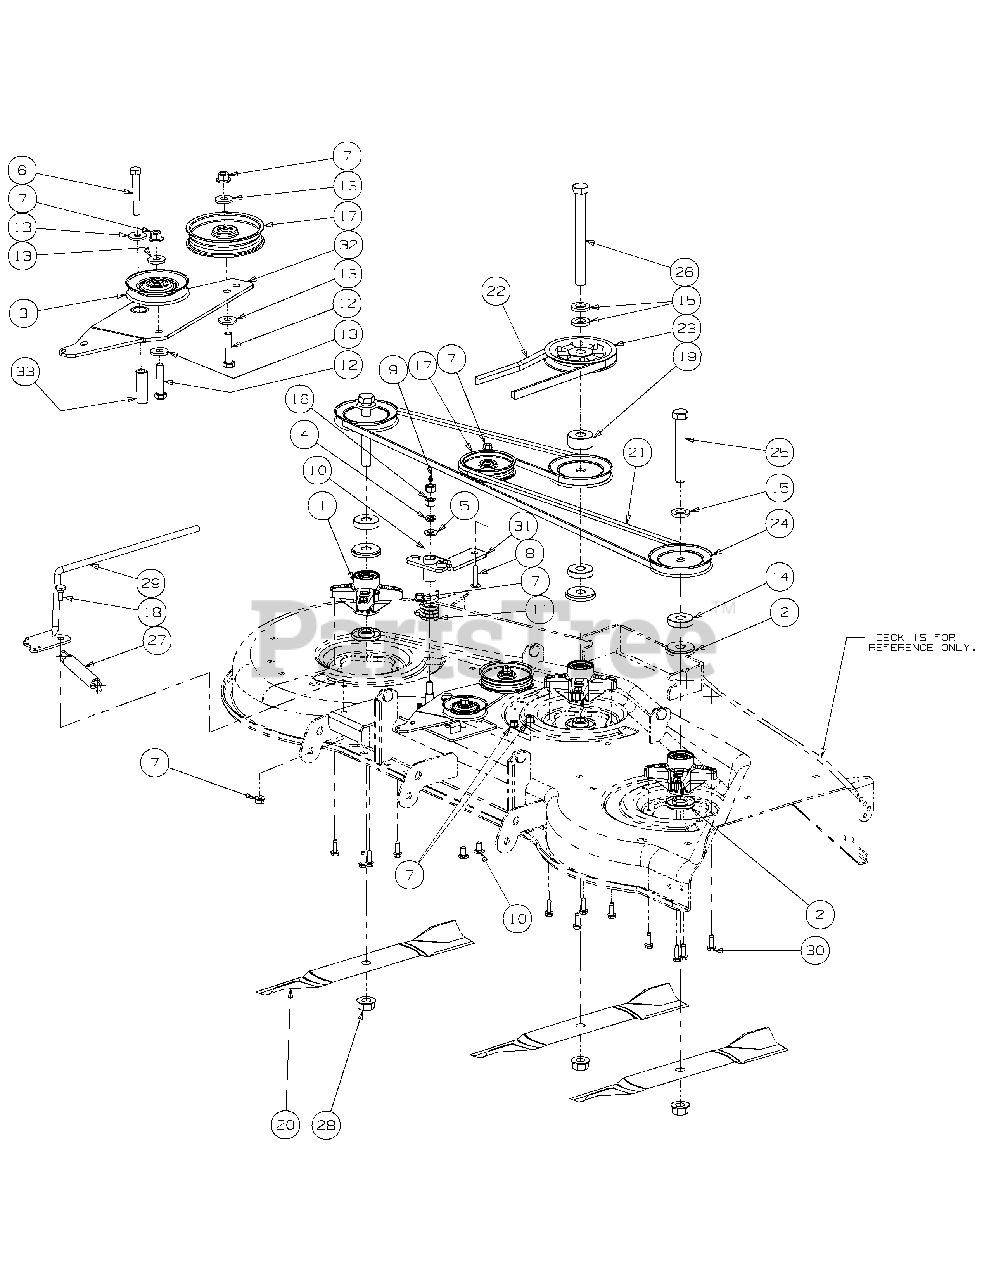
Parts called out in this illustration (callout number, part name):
1	Spindle Assembly
2	Spindle Spacer
3	V-Pulley, 3.50 OD
4	Lock Washer, 1/2
5	Washer, 1/2 Zinc
6	Hex Cap Screw, 3/8-16 x 2.50
7	Hex Nut, 3/8-16, Flange Lock
8	Hex Carriage Screw, 3/8-16, 1.50
9	Grease Fitting, 1/4-28 x 3/16
10	Carriage Bolt 3/8-16 x .75
11	Torsion Idler Spring
12	Hex Cap Screw, 3/8-16 x 1.750
13	Flat Washer, .406 ID, 1.0 OD, .105
14	Spacer, .76 ID x 2.00 OD x .477
15	Spacer .812 ID x .218
16	Hex Nut, 1/2-20
17	Flat Pulley
18	Shoulder Screw, .50x.27 Lg., 3/8-16
19	Spacer, .760 ID x 2.000 OD x 1.1
20	Hi-Lift Blade, 20.5, .756 ID
21	V Belt, A Section x 120.0
22	V Belt, B Section x 83.2
23	V-Pulley, 5.774 OD
24	Pulley, A Sect x 4.90
25	Spindle Bolt 3/4-16 x 5.50
26	Hex Cap Screw, 3/4-16, 7.50
27	Extension Spring, .98 OD x 5.00
28	Flange Hex Nut, 3/4-16
29	Spring Tension Rod Assembly
30	Self Tapping Screw 5/16-18 x 1.00
31	Idler Arm Assembly, Deck Spindle includes:
33	Spacer, .39 ID x .625 OD x 1.875
